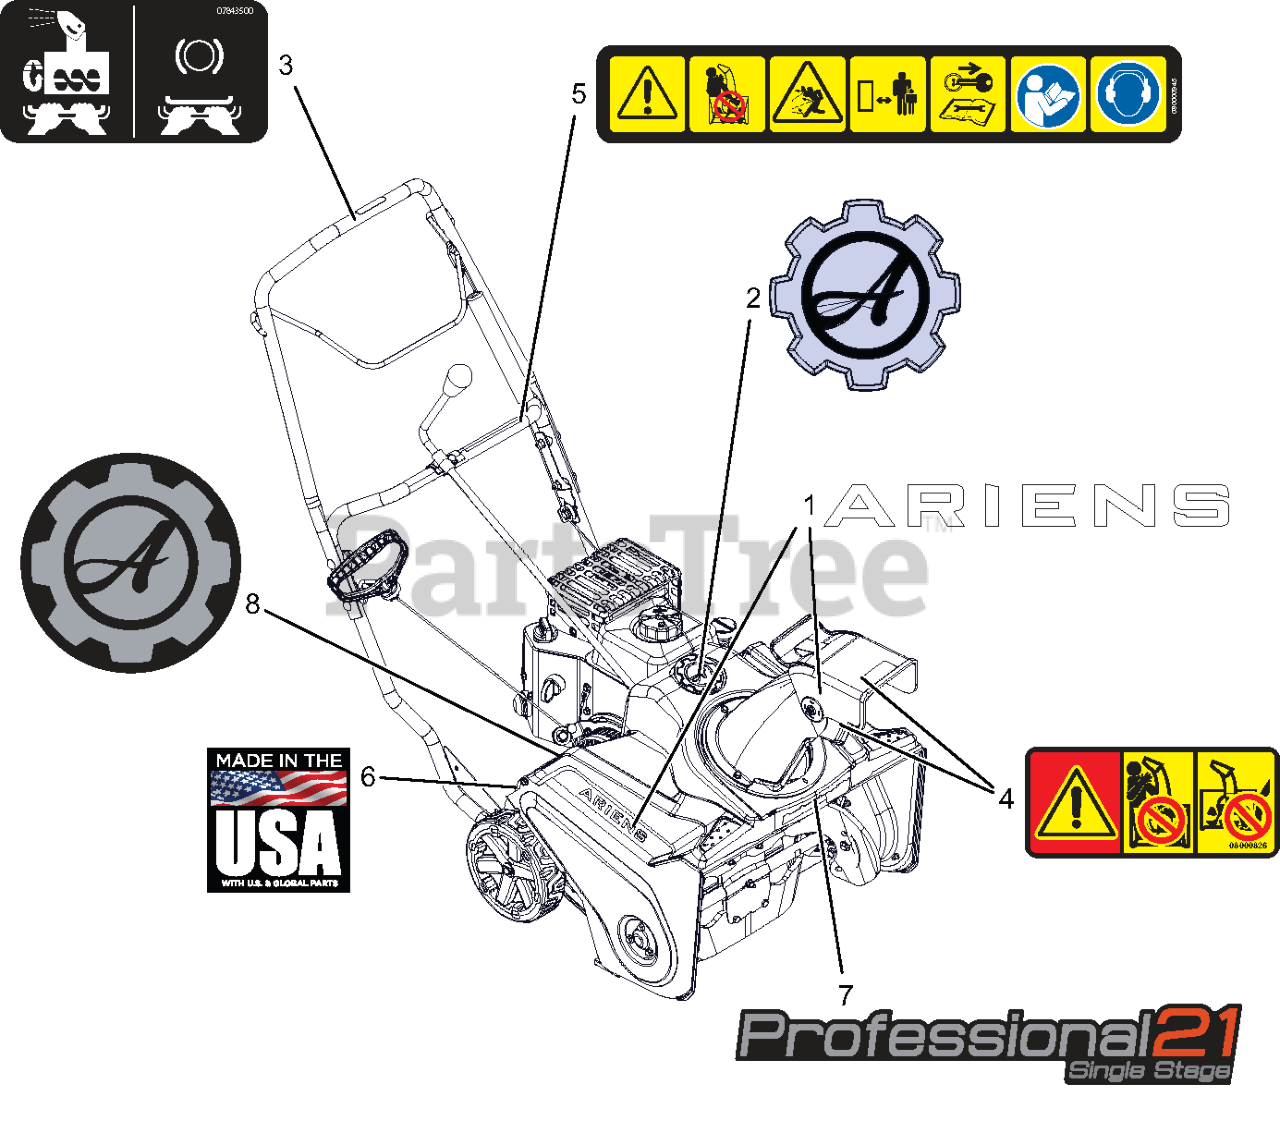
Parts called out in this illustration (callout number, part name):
1	DECAL, ARIENS (6.50")
2	DECAL- ARIENS GEAR BADGE
3	DECAL-AUGER/IMPELLER BAIL
4	DECAL, DANGER SINGLE STAGE
5	DECAL,DASH - SAFETY
6	DECAL, MADE IN USA
7	DECAL,COVER - PRO 21" CSS
8	DECAL, RECOIL- ARIENS LOGO
